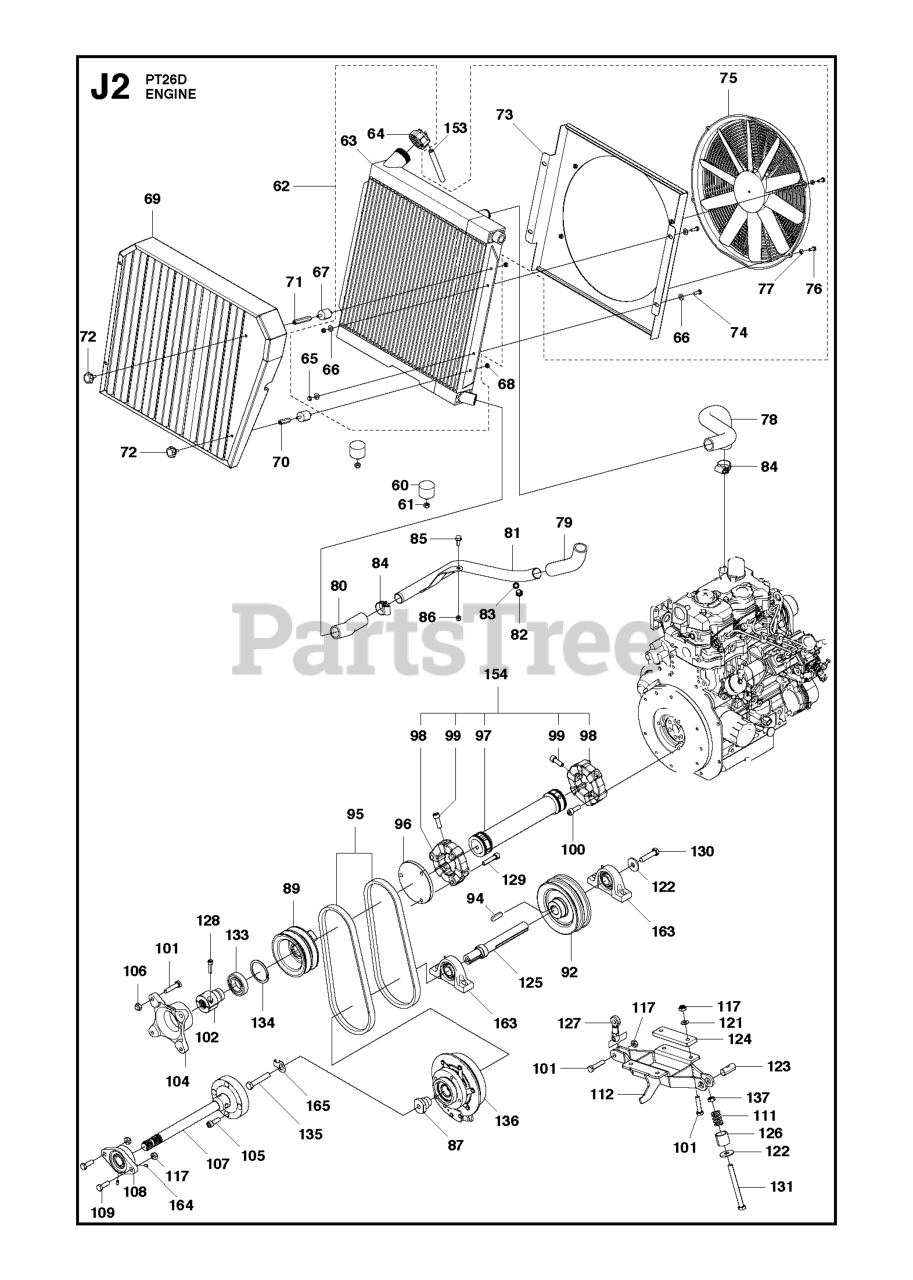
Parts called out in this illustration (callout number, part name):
60	ANTIVIBRATION ELEMENT
61	LOCKNUT M8
62	RADIATOR ASSY
65	LOCKNUT M6
66	WASHER - 15X7.3X1.6
67	ANTIVIBRATION ELEMENT RADIATOR
68	LOCKNUT M6
75	ELECTRIC FAN
76	Screw
77	WASHER - M6
78	HOSE COOLING WATER
79	HOSE COOLING WATER
80	HOSE COOLING WATER
81	TUBE COOLING WATER
82	SCREW EHHM
86	LOCKNUT M8
87	SPACER D-DRIVE
100	SCREW IHSCM M10X30 12.9 ZPB L
101	REPL BY 725 25 00-71
105	SCREW IHSCM M10X30 12.9 ZPB L
106	NUT
108	BEARING UNIT FYTB 25TF
117	NUT
121	WASHER
129	SCREW IHSCM M10X45 12.9 ZPB L
137	NUT
